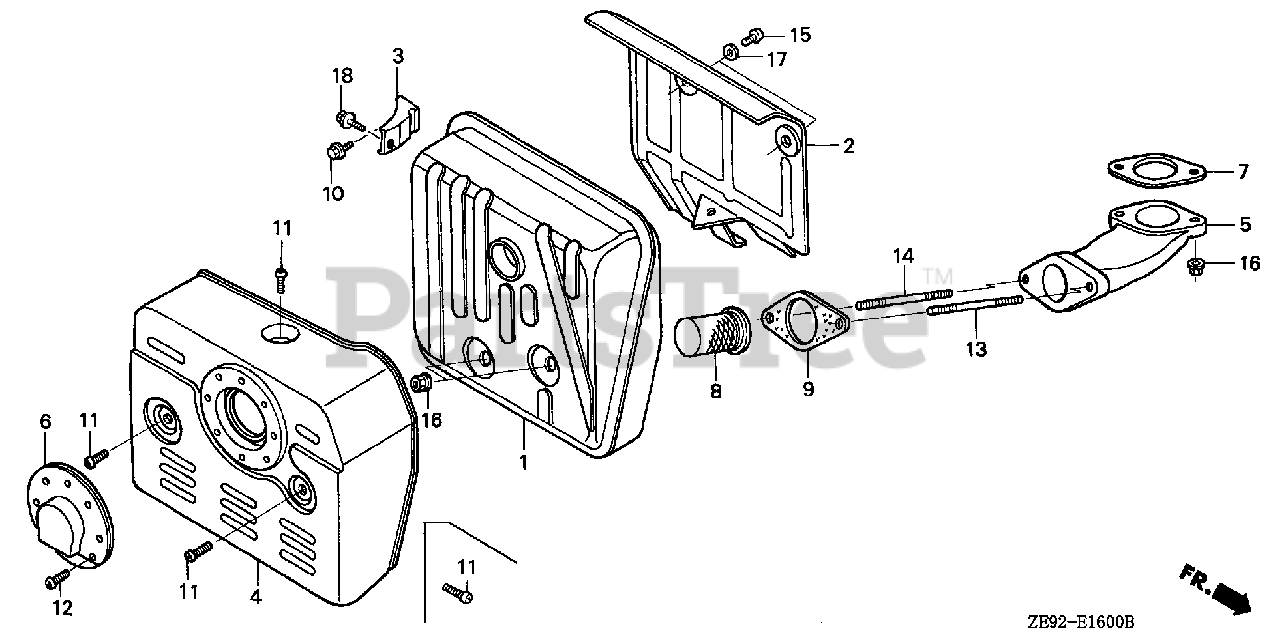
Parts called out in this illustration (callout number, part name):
2	SEPARATOR, MUFFLER
3	STAY, MUFFLER
4	PROTECTOR, MUFFLER
6	CAP, MUFFLER
7	GASKET, EX. PIPE
9	GASKET, EX. PIPE
10	BOLT, FLANGE (8X16)
11	SCREW, TAPPING (5X8)
12	SCREW, TAPPING (4X6)
13	BOLT, STUD (8X60)
14	BOLT, STUD (8X70)
15	SCREW, PAN (6X6)
16	NUT, FLANGE (8MM)
17	WASHER, PLAIN (6MM)
18	BOLT, FLANGE (8X14)
